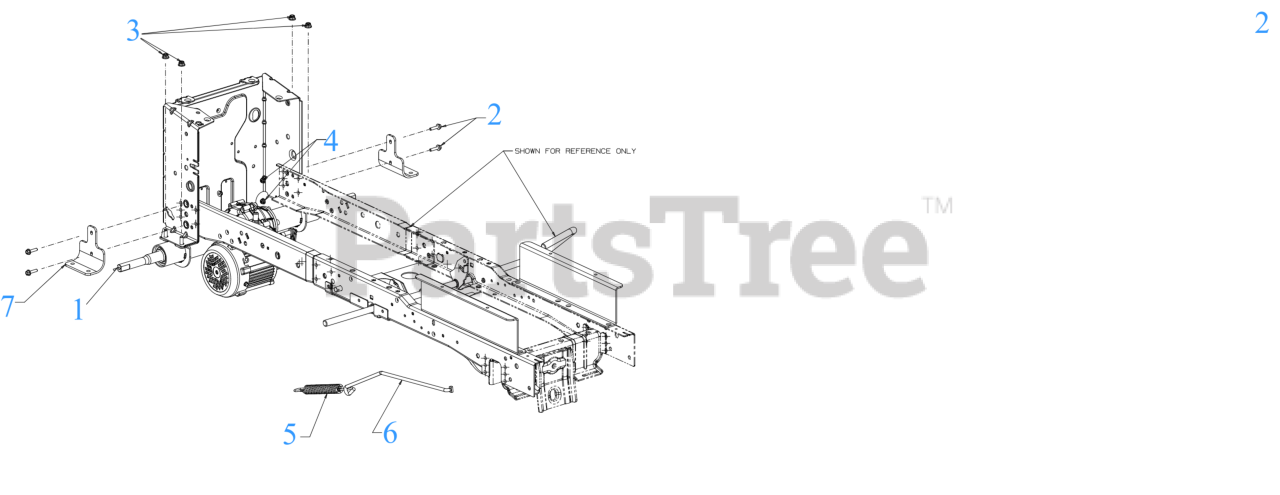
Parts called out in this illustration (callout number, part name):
1	TRANSMISSION
2	SCREW 1/4-20 x 1.0
3	FLANGE LOCK NUT 5/16-18
4	FLANGE LOCK NUT
5	EXTENSION SPRING 0.90 DIA x 8.14
7	TRANSMISSION BRACKET
